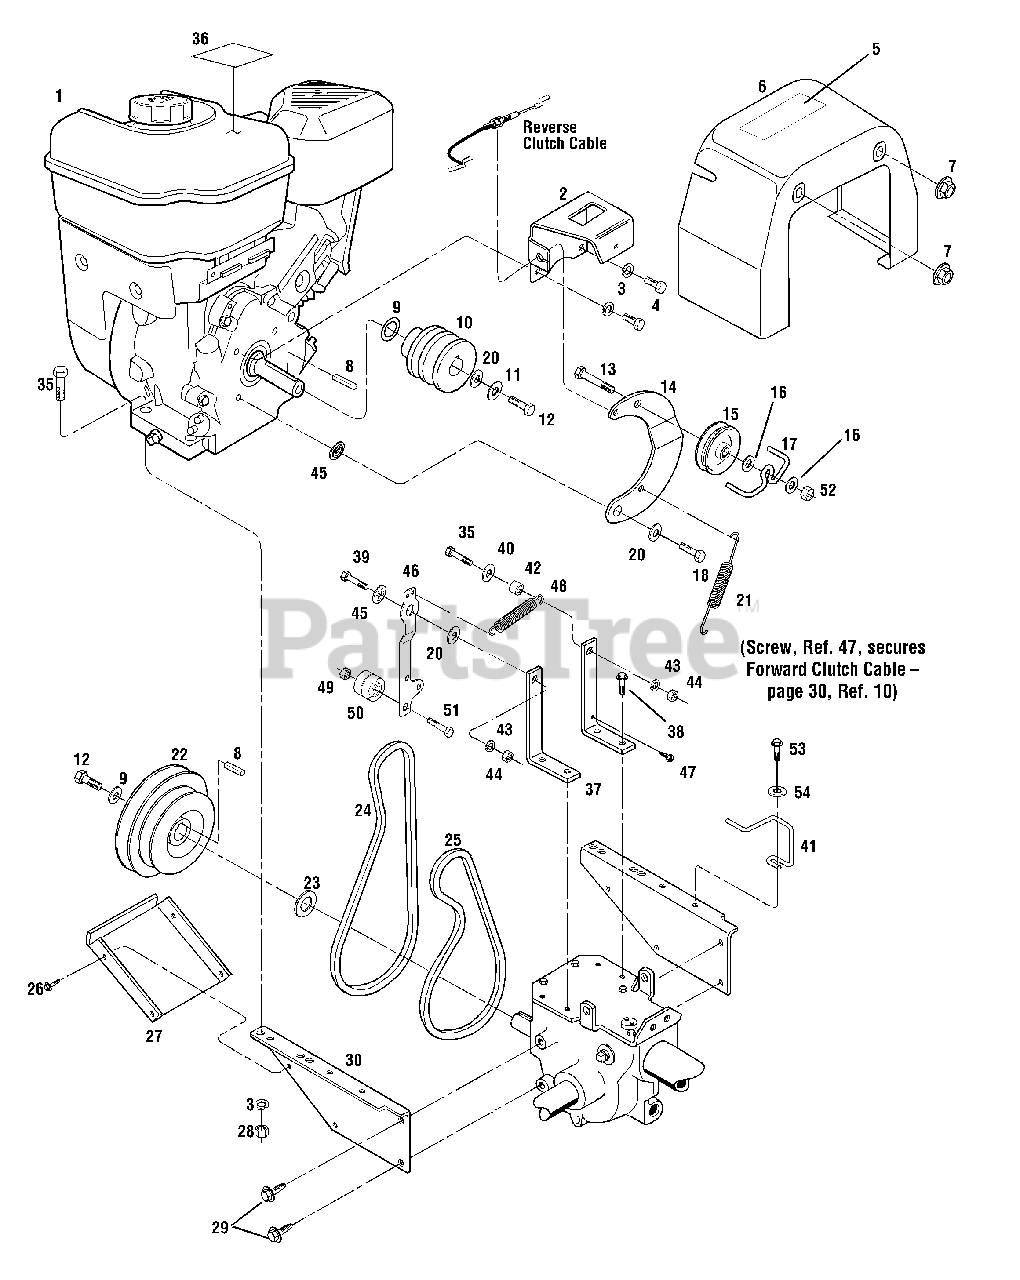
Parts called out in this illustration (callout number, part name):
1	Engine-standard recoil start
2	Bracket, Clutch Cable
3	Lockwasher-5/16
4	Hex Hd. Screw, 5/16-24 x 1/2
5	Decal, Hot Surfaces/Belt Warning
6	Cover
7	Flange Lock Nut, 5/16-18
8	Key, 3/16 x 1-1/2
9	Shim
10	Pulley, Engine Drive
11	Belleville Washer
12	Hex Hd. Screw, 5/16-24 x 1-1/8
13	Hex Hd. Screw, 5/16-18 x 2
14	Reverse Idler Arm
15	Pulley, Reverse Idler
16	Flat Washer, 5/16
17	Belt Guide, Wire Formed
18	Hex Head Screw, 5/16-24 x 1
20	Washer, Flat, 1-1/8
21	Spring, Reverse Return
22	Transmission Pulley
23	Support Washer
24	Reverse Clutch Belt
25	Forward Clutch Belt
26	Self-tapping Screw, #10-32 x 1/2,
27	Guard, Belts/Pulleys
28	Hex Nut, 5/16-18
29	Hex Flange Screw, 5/16-18 x 3/4
30	Engine Support Bracket, left side
35	Hex Hd. Screw, 5/16-18 x 1-1/2
36	Decal, Stabilization
37	Mounting Bar
38	Hex Flange Screw, 5/16-18 x 1
39	Hex Hd. Screw, 5/16-18 x 2-1/4
40	Flat Washer, 5/16'
41	Belt Guide, Pony
42	Pivot Bushing
43	Lockwasher, 5/16
44	Hex Nut, 5/16-18
45	Washer, Shoulder
46	Idler Arm, Forward Tiller Direction
47	Screw, self tapping, #10-24
48	Spring
49	Hex Locknut, 5/16-18
50	Idler Pulley, Forward
51	Screw, 3/8-16 x 1-3/4
52	Hex Lock Nut, 5/16-18
53	Screw, 1/4-20 x 3/4
54	Flat Washer-1/4
